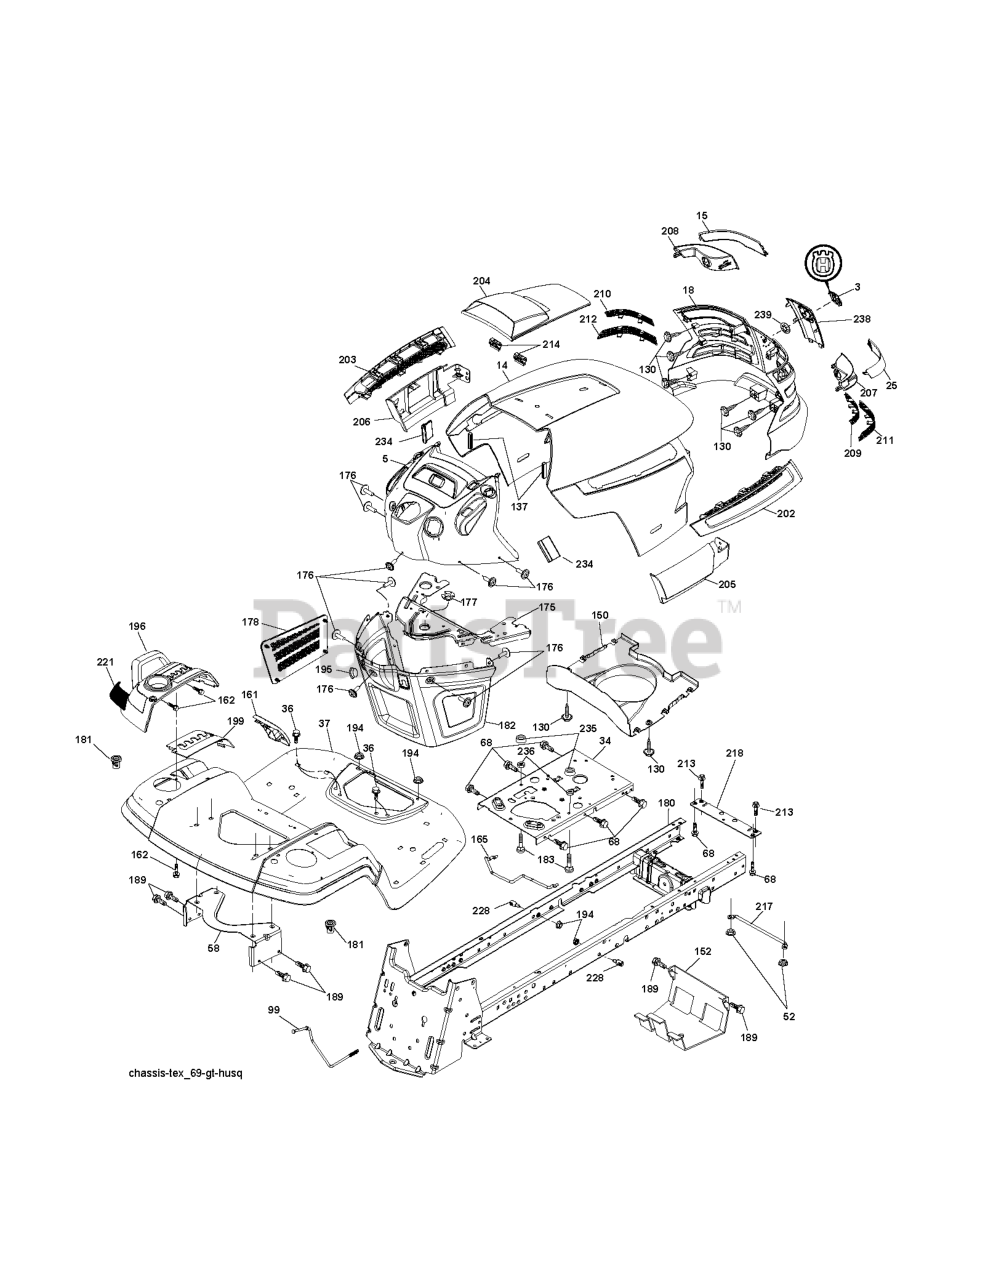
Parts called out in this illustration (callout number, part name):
3	RP LOGO
5	DASH.ASM.HUSQ.GT.E.RECT.W/CK
14	HOOD
15	LENS.LH.TEX.GT.HUSQ.CL
18	GRILL.ASM.HUSQ.TG/CRD.W/TRIM
25	LENS.RH.TEX.GT.HUSQ.CL
34	PLATE.ENGINE.WELDED.CHASSIS
36	SCREW 5/16"
37	FENDER.PNT.TX.GT.CH/FW.ORANGE
52	LOCKNUT
58	BRKT.SUPPORT.FNDR/TANK
68	Screw 5/16-18 x 1/2 Hex, Self Tapping 5/16-18 x 1/2
99	ROD BYPASS ASM.
130	SCREW
137	BUMPER DASH
150	AIR.DUCT.HOOD.TEX.GT.HUSQ
152	SHIELD.BROWNING.W/TEX
161	CONSOLE.FUEL.WINDOW.HU
162	SCREW.HI-LO.CONSOLE
165	SUPPORT.TANK.REAR.W/TEX
175	PLATE.CROSSMEMBER.HUSQ
176	SCREW.#10-24X5/8.RN.QU
177	BUSHING, STEERING
178	CARGO.ASM.NET.TXGT.W/C
180	CHASSIS.GT.SLOPED.DRAWBAR.
181	BUSHING.MNT.FEND.CRGO.
182	DASH.LOWER.COMMON.12V.ADAPTOR
183	BOLT.5/16-18X1-1/4 FULL.THREAD
189	SCREW
194	NUT LOCK HEX FLANGE 5/16-18
195	PLUG.HOLE.DASH.LOWER.12V.BLK
196	RP CONSOLE.ASM.DECKLFT.W/
199	PLATE.DECK.LIFT.HUSQVARNA.GT
202	VENT.SIDE.HOOD.HUSQ.RH.GREY
203	VENT.SIDE.HOOD.HUSQ.LH.GRAY
204	HOOD VENT
205	SKIRT.HOOD.SIDE.HUSQ.RH.GREY
206	SKIRT.HOOD.SIDE.HUSQ.LH.GREY
207	BEZEL.RH.TEX.GT.HUSQ
208	BEZEL.LH.TEX.GT.HUSQ
209	INSERT.HEX.GRILL.HUSQ.GREY
210	INSERT.HEX.GRILL.HUSQ.
211	INSERT.HEX.GRILL.HUSQ.
212	INSERT.HEX.GRILL.HUSQ.
213	BOLT
214	CLIP.RETAINER.TINNER.
217	ROD.PIVOT.HOOD
218	X-PIECE.HOOD.STOP.NON/
221	REFLECTOR.LH.TEX GT HU
228	STUD.FASTNER.W/ANTI-ROTATE
234	BUMPER.HOOD.TEX.HUSQVARNA
235	SPACER FENDER
236	NUT.CENTERLOCK.5/16-
238	TRIM.HUSQ.TG/CRD.SERVICE
239	NUT PUSH M
